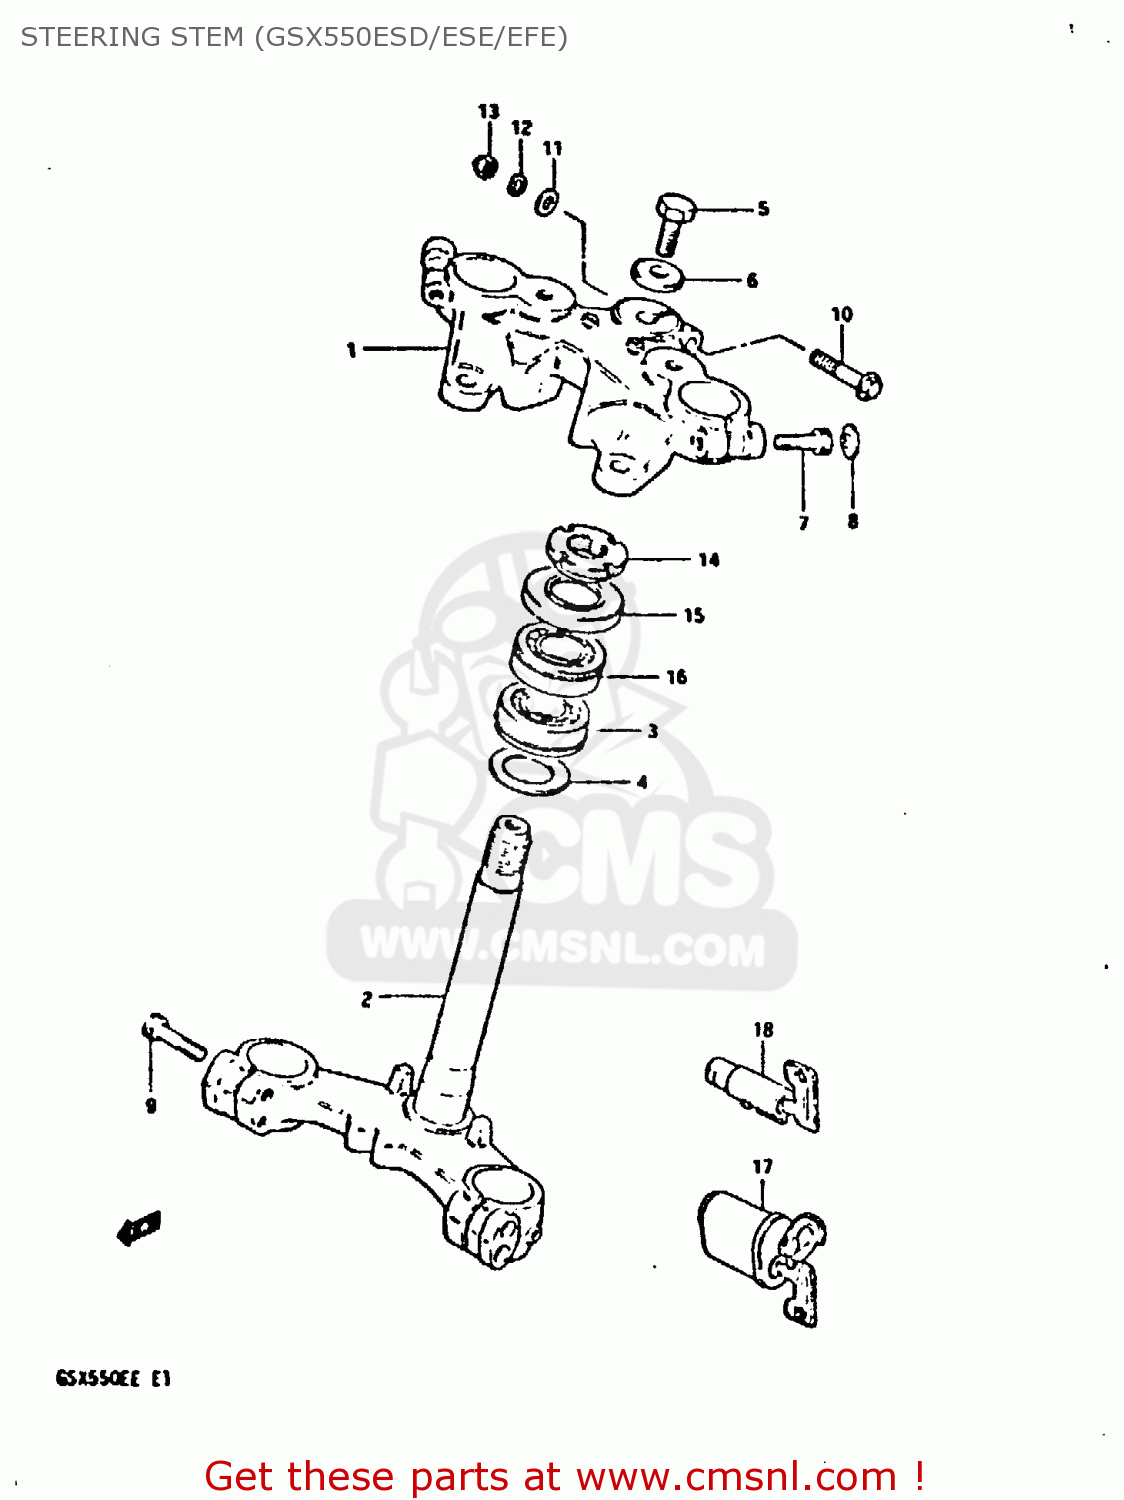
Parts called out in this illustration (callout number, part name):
1	HEAD,STEERING STEM
2	STEM,STEERING
3	BEARING
4	WASHER,THRUST
5	NUT,STEM HEAD
6	WASHER,STEERING STEM B
7	BOLT
8	CAP(OD:20)
9	BOLT, REAR (8X30)
10	BOLT, UPPER
11	WASHER,8.5X16X
12	LOCK WASHER
13	NUT,M8X1.25X12
14	NUT,STEERING STEM
15	DUST SEAL,STEERING UPR
16	TAPER,ROLLER BEARING
